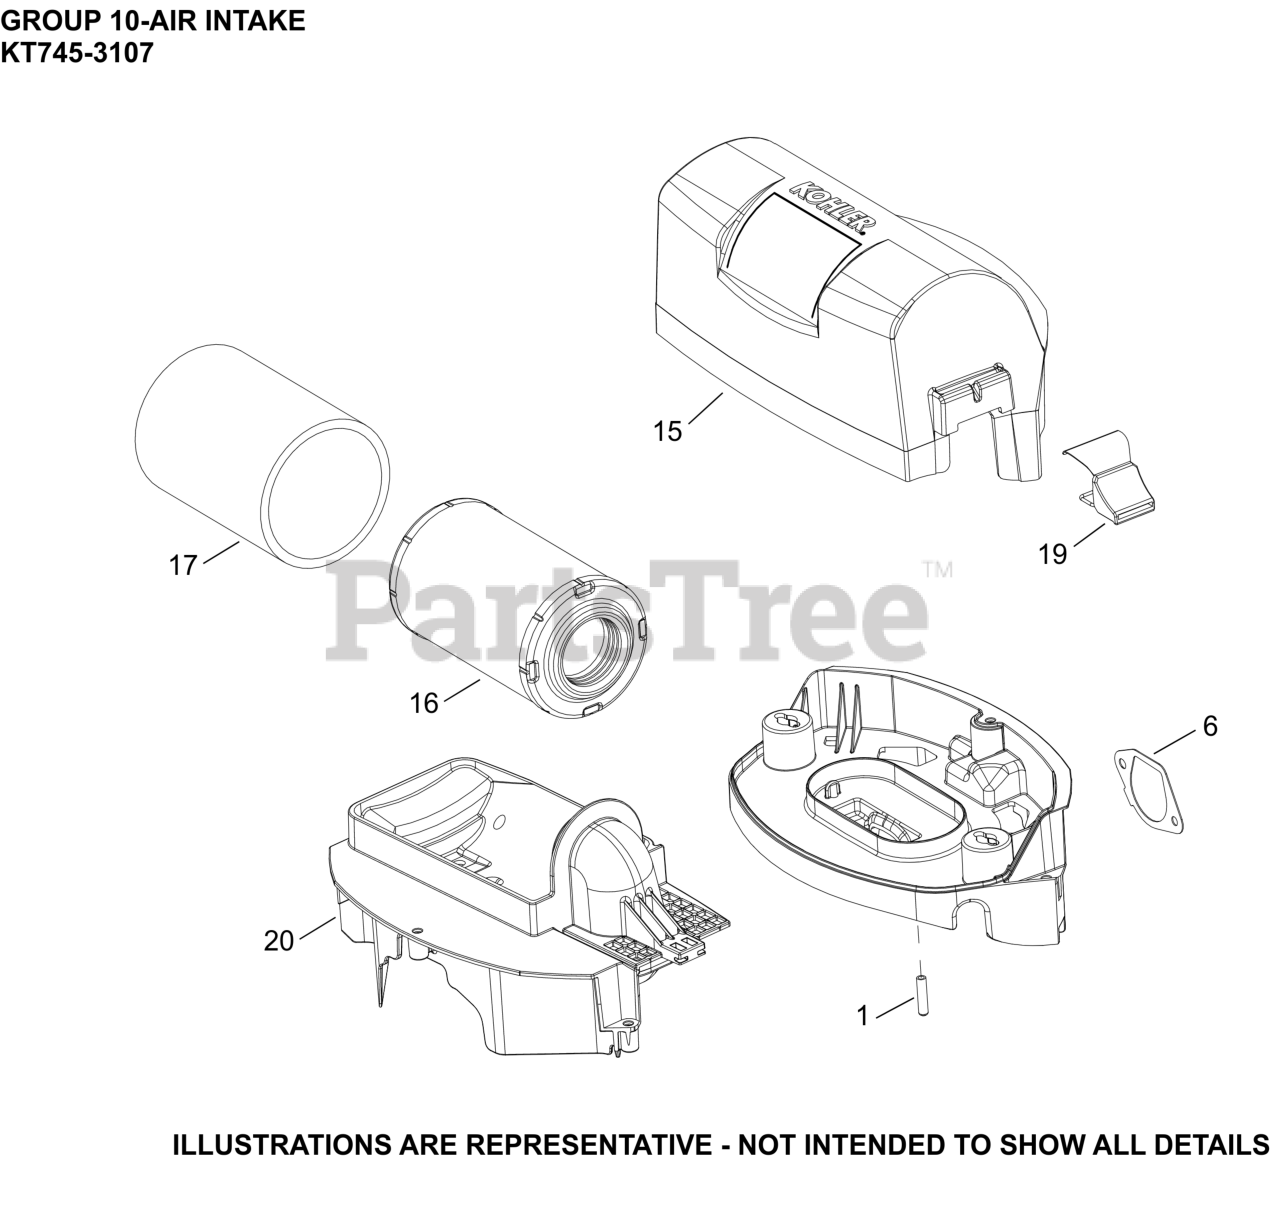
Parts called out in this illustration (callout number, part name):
1	CAP, MASKING
6	GASKET, AIR CLEANER BASE
15	COVER, AIR CLEANER
16	ELEMENT, AIR FILTER
17	ELEMENT, PRE-CLEANER
19	LATCH ASSY, AIR CLEANER COVER
20	BASE, ASM. AIR CLEANER (CYLINDRICAL)
